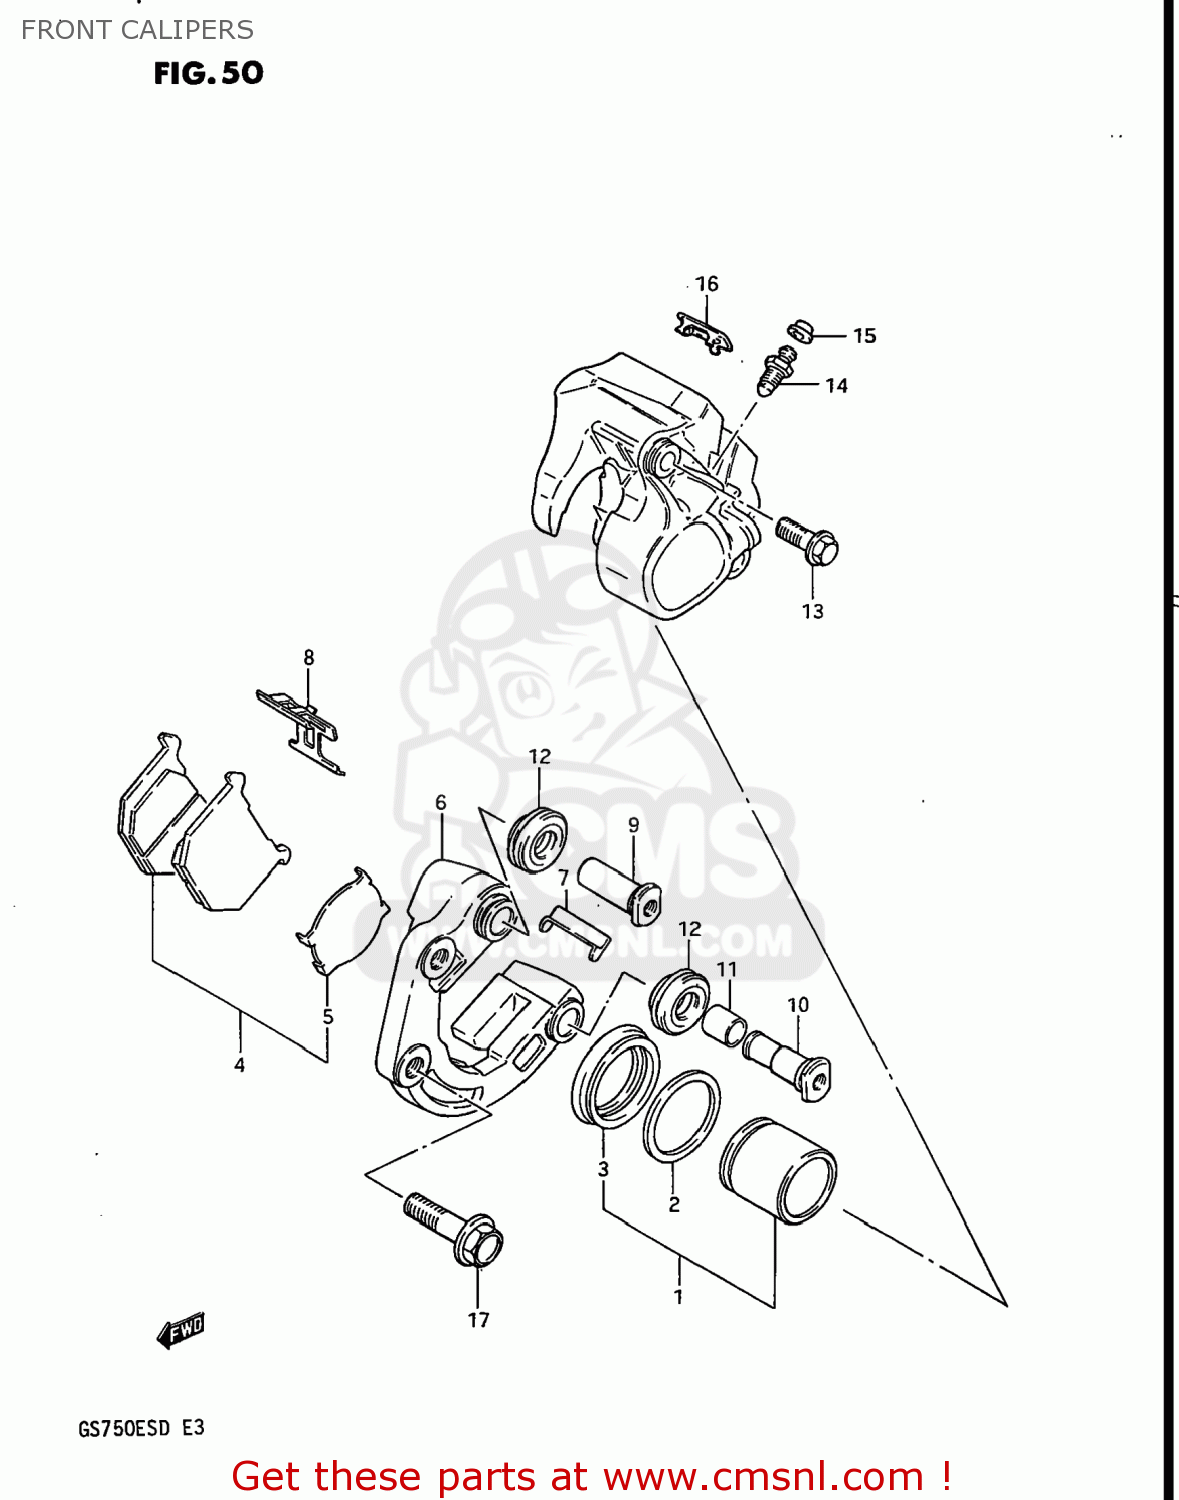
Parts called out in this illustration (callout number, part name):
1	PISTON SET
2	SEAL,PISTON
3	BOOT,PISTON
4	PAD & SHIM SET (NAS)
5	SHIM,PAD
6	CARRIER,CALIPER,LEFT
7	GUIDE,PAD
8	SPRING,PAD
9	AXLE NO.1
10	AXLE NO.2
11	BUSH,AXLE
12	BOOT,AXLE
13	BOLT
14	BLEEDER
15	CAP,BREATHER
16	COVER
17	BOLT
